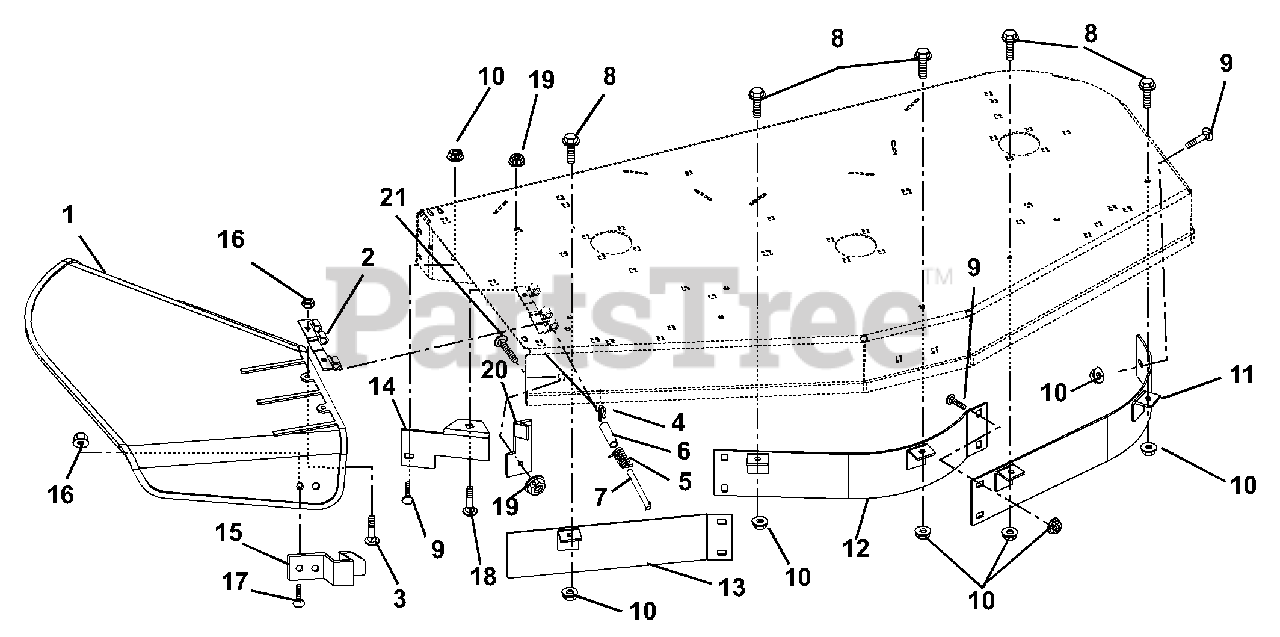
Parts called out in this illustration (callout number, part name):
1	DEFLECTOR, CHUTE
2	HINGE PLATE
3	@BLT-RDHDSQNK .25-20X.75 G5YZ
4	PIN-HAIR INT .08X.18X1.18 YWZC
5	SG-TORS .095X.50X 1.0
6	BSHG-SLV .334 X .502 X 1.437
7	PIN, 5/16 X 5.80"
8	BLT-SERHFWH .312-18X.75 YWZC
9	@BLT-RHDSSQNK .31-18X.75 G5YZ
10	@NUT-LK-NYL-FLG .31-18 YWZC
11	BAFFLE - LEFT FRONT - 40"
12	BAFFLE - CENTER FRONT - 40"
13	BAFFLE - RIGHT FRONT - 40"
14	DEFLECTOR-40"
15	FLAT SPRING
16	@NUT-LK-TOP-FLG .25-20 YWZC
17	@BLT-RDHDSQNK .25-20X.50 G5YZ
18	@BLT-RDHDSQNK .38-16X1.00 G5YZ
19	@NUT-LK-NYL-FLG .38-16 YWZC
20	BRACKET, CHUTE LOCK
21	@BLT-RDHDSQNK .38-16X1.50 G5YZ
